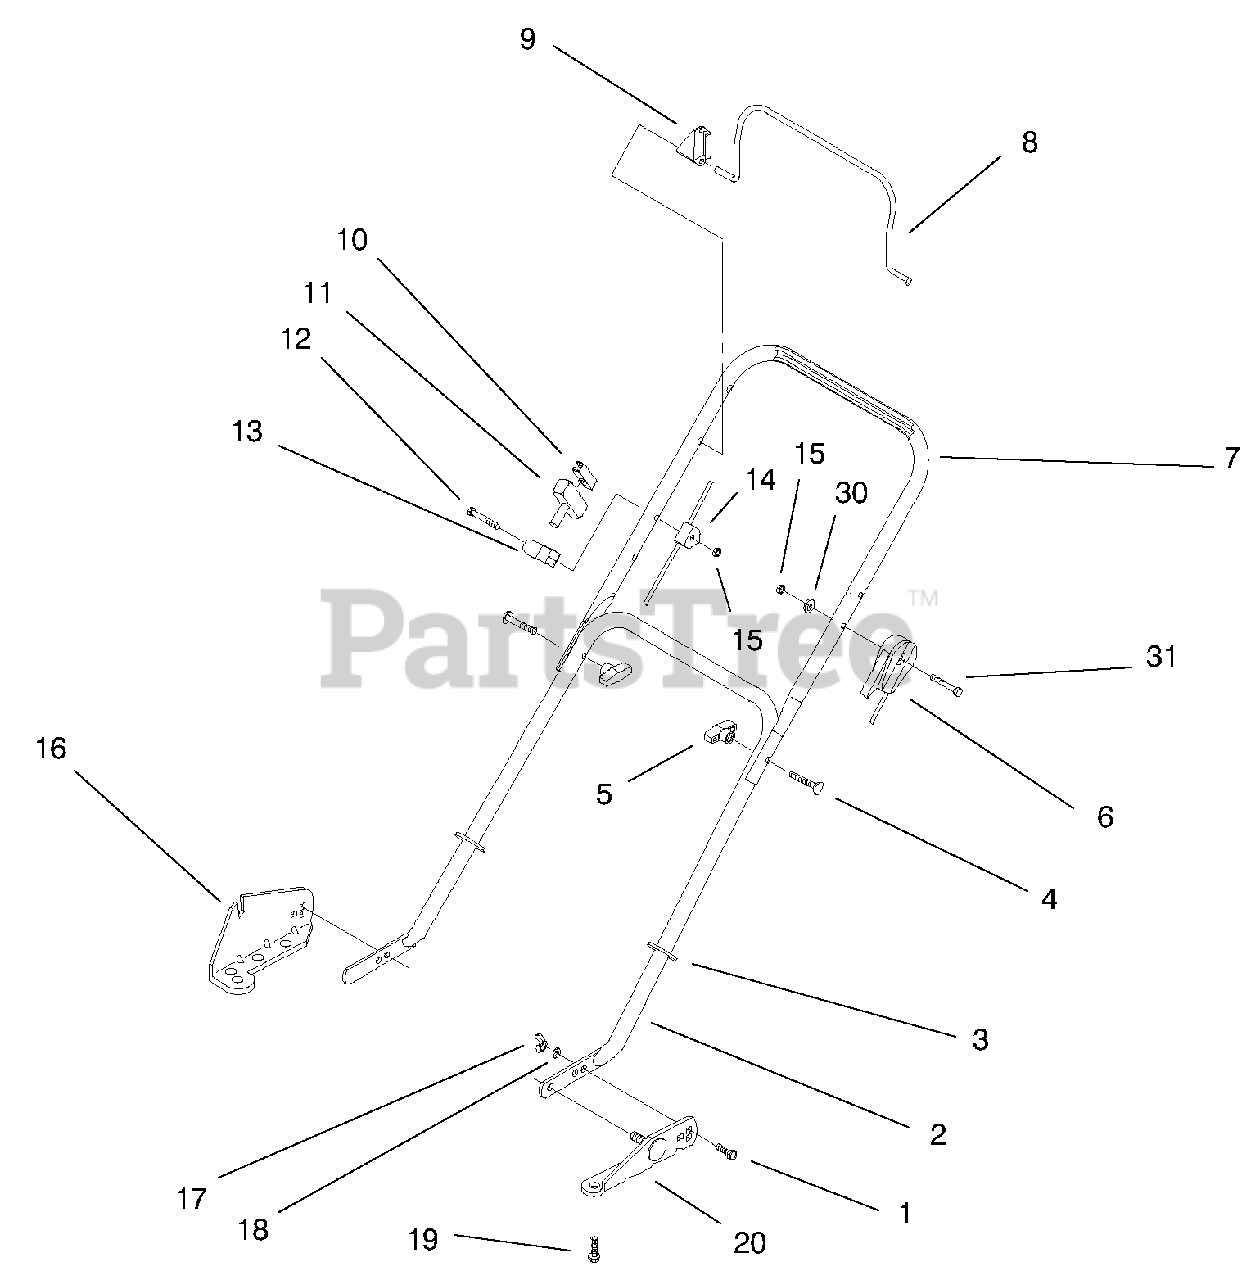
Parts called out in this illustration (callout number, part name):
1	SCREW-CARR
2	Handle-Lower
3	TIE-STRAP
5	KNOB-HANDLE
6	CABLE - THROTTLE
7	HANDLE - UPPER
8	BAIL - BRAKE
9	STOP-PIVOT
10	CLIP-STARTER
11	HANDLE-START
12	SCREW-HH
13	GUIDE-ROPE
14	CABLE - FLYWHEEL BRAKE
15	NUT-LOCK, NI
16	RH BRACKET & PIN ASM
18	WASHER-LOCK
20	LH BRACKET & PIN ASM
30	WASHER
31	SCREW-HH
